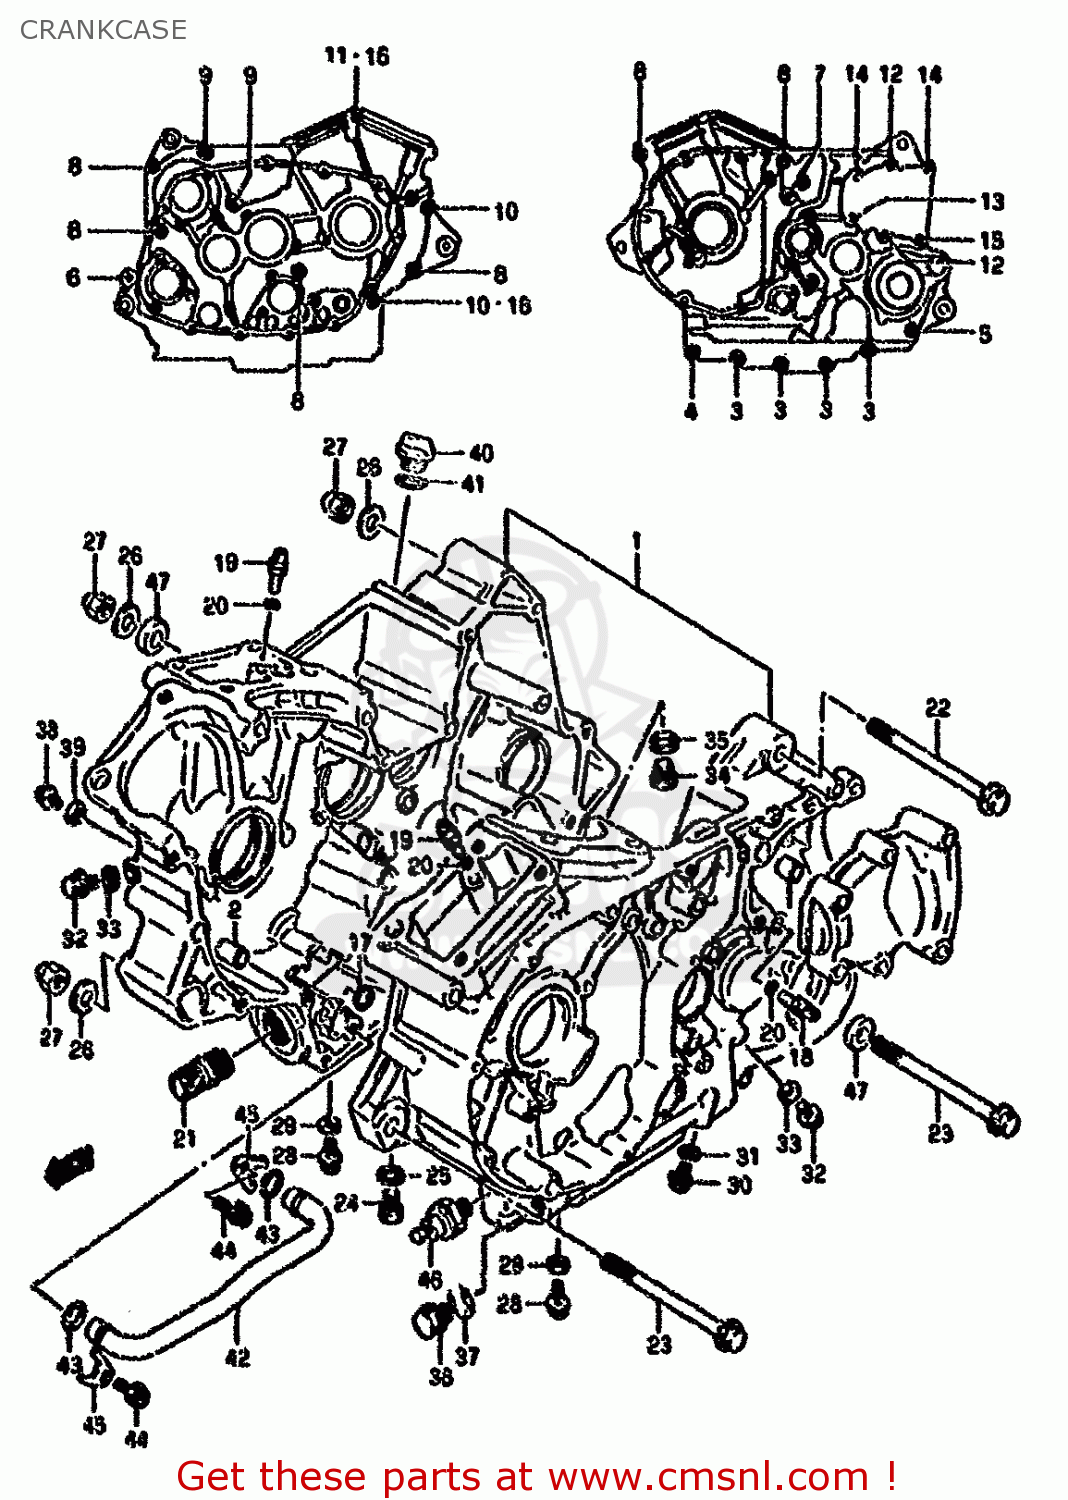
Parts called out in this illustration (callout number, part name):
1	CRANKCASE SET
2	PIN (11X20)(SUS)
3	BOLT
4	BOLT
5	BOLT
6	BOLT
7	BOLT
8	BOLT
9	BOLT(8X120)
10	BOLT(8X105)
11	BOLT 8X160
12	BOLT
13	BOLT
14	BOLT
15	BOLT
16	GASKET 8.2X14X1 (NAS)
17	O RING(D:1.9,ID:12.6)
18	JET,OIL GALLERY
19	JET,AIR(14)
20	O RING(D:1.2,ID:4)
21	UNION,OIL STAND
22	BOLT(10X130)
23	BOLT,ENGINE MOUNTING (10X170)
24	BOLT
25	GASKET(12.1X16.2X3.7) (NAS)
26	WASHER
27	NUT
28	BOLT
29	GASKET(8.2X14X1).6 (NAS)
30	PLUG
31	GASKET(10X14X3.6) (NAS)
32	BOLT
33	GASKET(5.8X13X1.2) (NAS)
34	PLUG
35	GASKET(16X22X2) (NAS)
36	PLUG
37	GASKET(13.8X18.8X4.8) (NAS)
38	BOLT
39	GASKET(8.2X14X1).6 (NAS)
40	PLUG
41	O RING(D:3.1,ID:16.8)
42	PIPE,OIL GALLERY
43	O RING(D:3.1,ID:14.8)
44	BOLT
45	CLAMP,OIL PIPE
46	SWITCH ASSEMBLY,OIL PRESSURE
47	SPACER,ENG MOUNT NO.2
